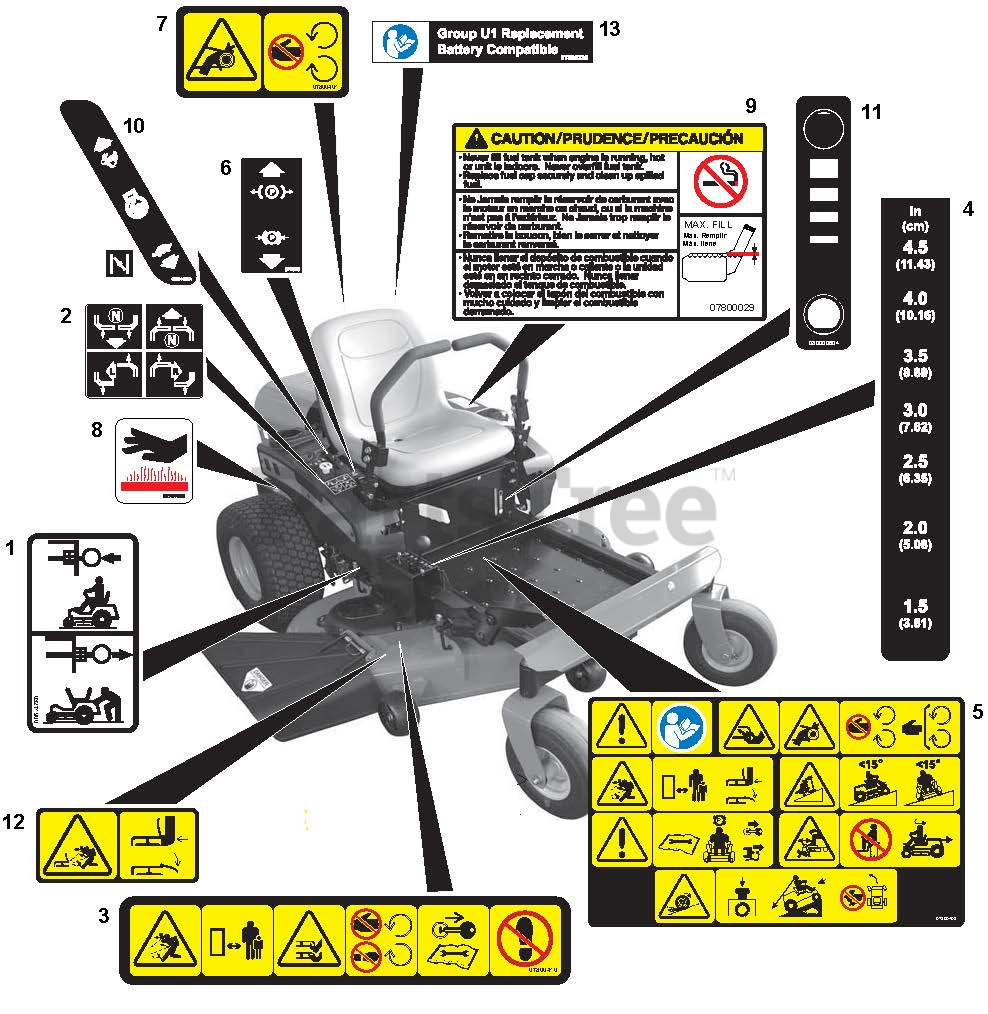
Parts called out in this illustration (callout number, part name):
1	DECAL, TRANSMISSION DISCONNECT
2	DECAL, INSTRUCTIONAL-STEERING
3	DECAL, DECK SAFETY
4	DECAL, HEIGHT OF CUT
5	DECAL, MAIN SAFETY
6	DECAL, PARKING BRAKE LEVER
7	DECAL, SAFETY - GUARDING
8	DECAL, HOT SURFACE
9	DECAL-FUEL, WARNING
10	DECAL, SPEED CONTROL
11	DECAL, FUEL LEVEL
12	DECAL, SAFETY - DECK GUARDING
13	DECAL, U1 BATTERY REPLACEMENT
